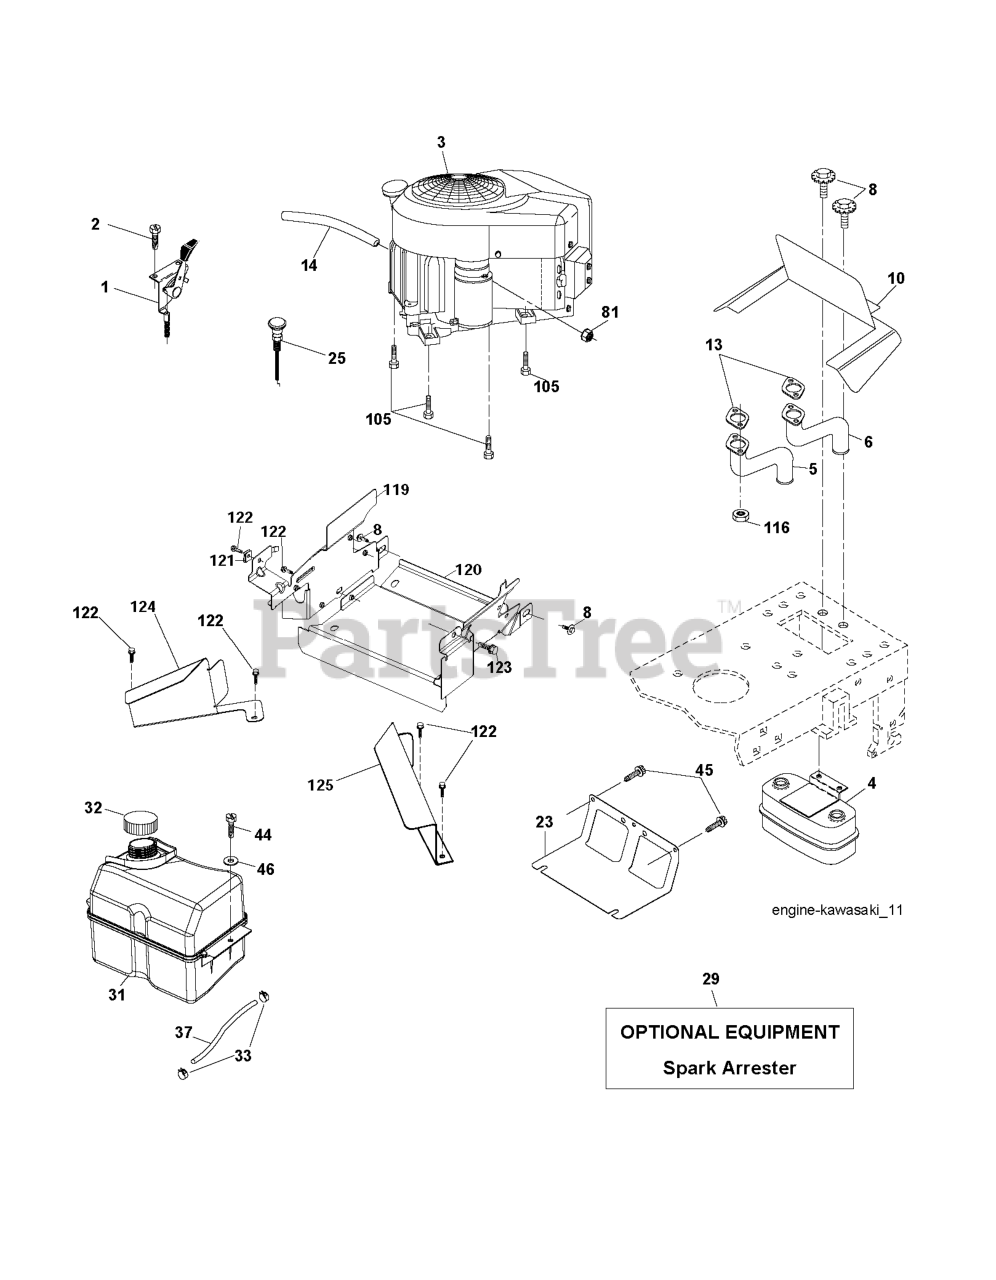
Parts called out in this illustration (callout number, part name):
1	THROTTLE CABLE
2	SCREW
4	MUFFLER.TWIN.CYL.LOW.TONE
5	EXHAUST TUBE LH KAWI
6	EXHAUST TUBE RH KAWI
8	BOLT.5/16-18UNCX3/4 W/SEMS.BLK
10	RP SHIELD HEAT MUFFLER
13	GASKET.EXHAUST.KAWASAKI.15-1
14	TUBE, DRAIN OIL ASM.
23	SHIELD.BROWNING.DBR.GUARD
25	CONTROL, CHOKE
29	KIT.SPARK ARRESTOR 794945 B&S
31	TANK.ASM.FUEL.FR.2.5GA.
32	FUEL CAP
33	HOSE CLAMP
37	LINE.FUEL.20
44	SCREW HEXWSHR 1/4-20X3/4
45	SCREW, 3/8-16X3/4
46	WASHER
81	NUT
105	SCREW 3/8-16X1
116	NUT.HEX.FLANGE.TOPLOCK
119	LENKRAD
120	GUARD 532199767
122	SCREW.1/4-20X5/8
123	SCREW, 5/16-18 X 1/2
